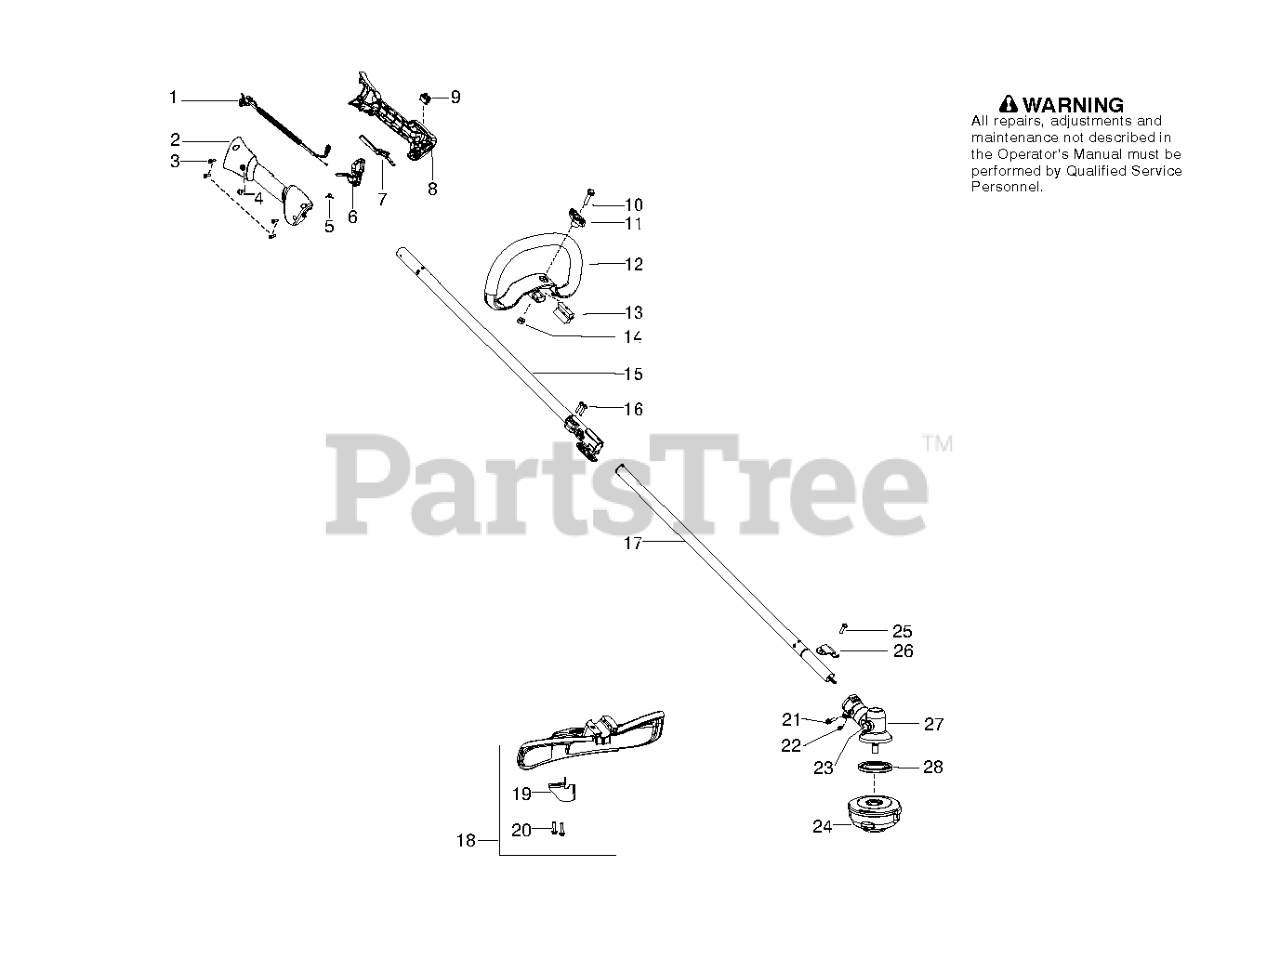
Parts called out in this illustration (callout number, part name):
1	ASSY CABLE / WIRE HARNESS
2	HSG THROTTLE RIGHT HVA
3	SCREW M4 X 1.75 PT 16MM
4	SCREW-10-14 X 1/2 PLASTITE
5	SPRING TRIGGER
6	TRIGGER THROTTLE HVA ORANGE
7	THROTTLE LOCKOUT HVA ORANGE
8	HSG THROTTLE LEFT HVA
9	SWITCH
10	SCREW M6X50
12	ASSY LOOP HANDLE
13	SPACER PLASTIC
15	DRIVESHAFT
17	KIT LOWER SHAFT
18	KIT COBI SHIELD
19	Limiter - Line
21	SCREW - CARB. ADAPTOR
23	PLUG GREASE 9MM
24	T25 TRIM HEAD 10MM LH
25	SCREW 1/4-20 X 7/8 (TAP
26	BRACKET SHIELD STRAIGHT SHAFT
27	ASSY GEARBOX
28	DRIVE DISC
